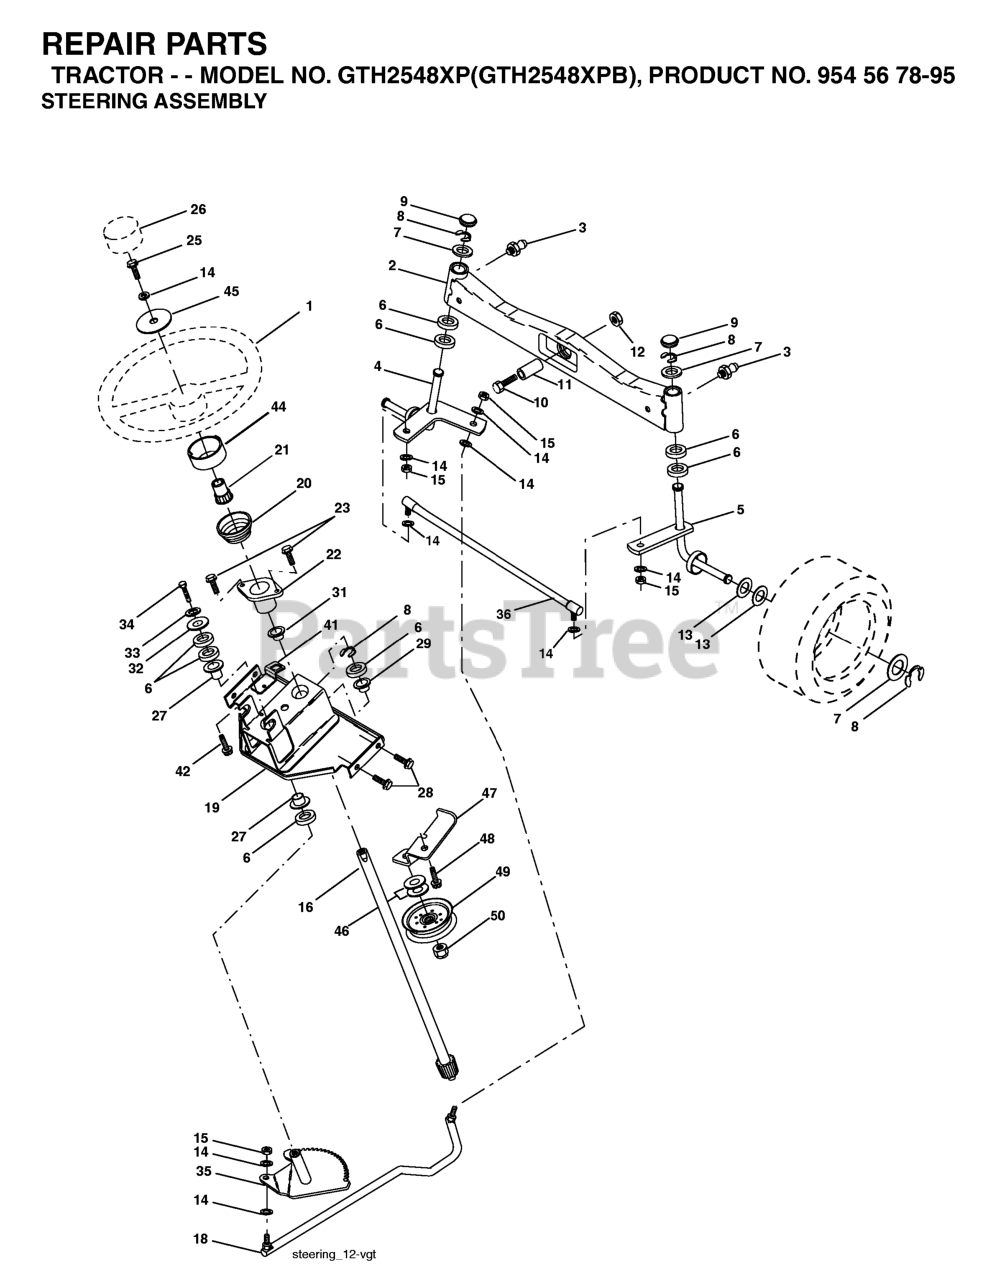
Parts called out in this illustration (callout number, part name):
1	STEERING WHEEL
2	AXLE.FRONT.CAST.MACHINE.W/ZERK
3	ZERK M
4	SPINDLE ASSY LH
5	SPINDLE ASM RH
6	THRUST WASHER
9	CAP.SPINDLE.BLACK
10	Bolt, Hex 5/8 -11 x 2 - 3/4 Gr. 5
11	TUBE, PIVOT AXLE
12	NUT-LOC,FLANGE LT
14	WASHER, LOCK 3/8
15	GRIPCO NUT
16	SHAFT ASM, STEERING
18	DRAGLINK, BALL JOINT (3SPG1401
19	SUPPORT ASM., STEERING VGT
20	BOOT, STEERING
21	STEERING WHEEL ADAPTOR
22	BUSHING, STRG. BLK
23	SCREW.TT.#10-32X.5.3/8.FLANGE
25	BOLT
26	CAP.WHEEL.STEERING.GREY
27	BRNG T
28	SCREW, 3/8-16X3/4
29	BEARING-FLANGE GT
31	BUSHING.NYLINER.
33	WASHER.LOCK.HVY.HLCL.SPR.5/16
34	BOLT.FIN.HEX.5/16-18X3/4
35	GEAR.ASM.SECTOR.
36	ROD.TIE.NON-ADJUSTABLE
41	BRACKET INTERLOCK
42	Screw 5/16-18 x 1/2 Hex, Self Tapping 5/16-18 x 1/2
44	EXTENSION STEERING PREMIUM
45	Washer 13/32 x 1-1/20 x 11 Gauge
47	BRKT.ASM.IDLER.STATIONERY
48	SCREW 3/8-16X3/4
49	PULLEY.IDLER.FLAT.46.PR.DR.
50	NUT LOCK FLG 3/8-16 UNC
